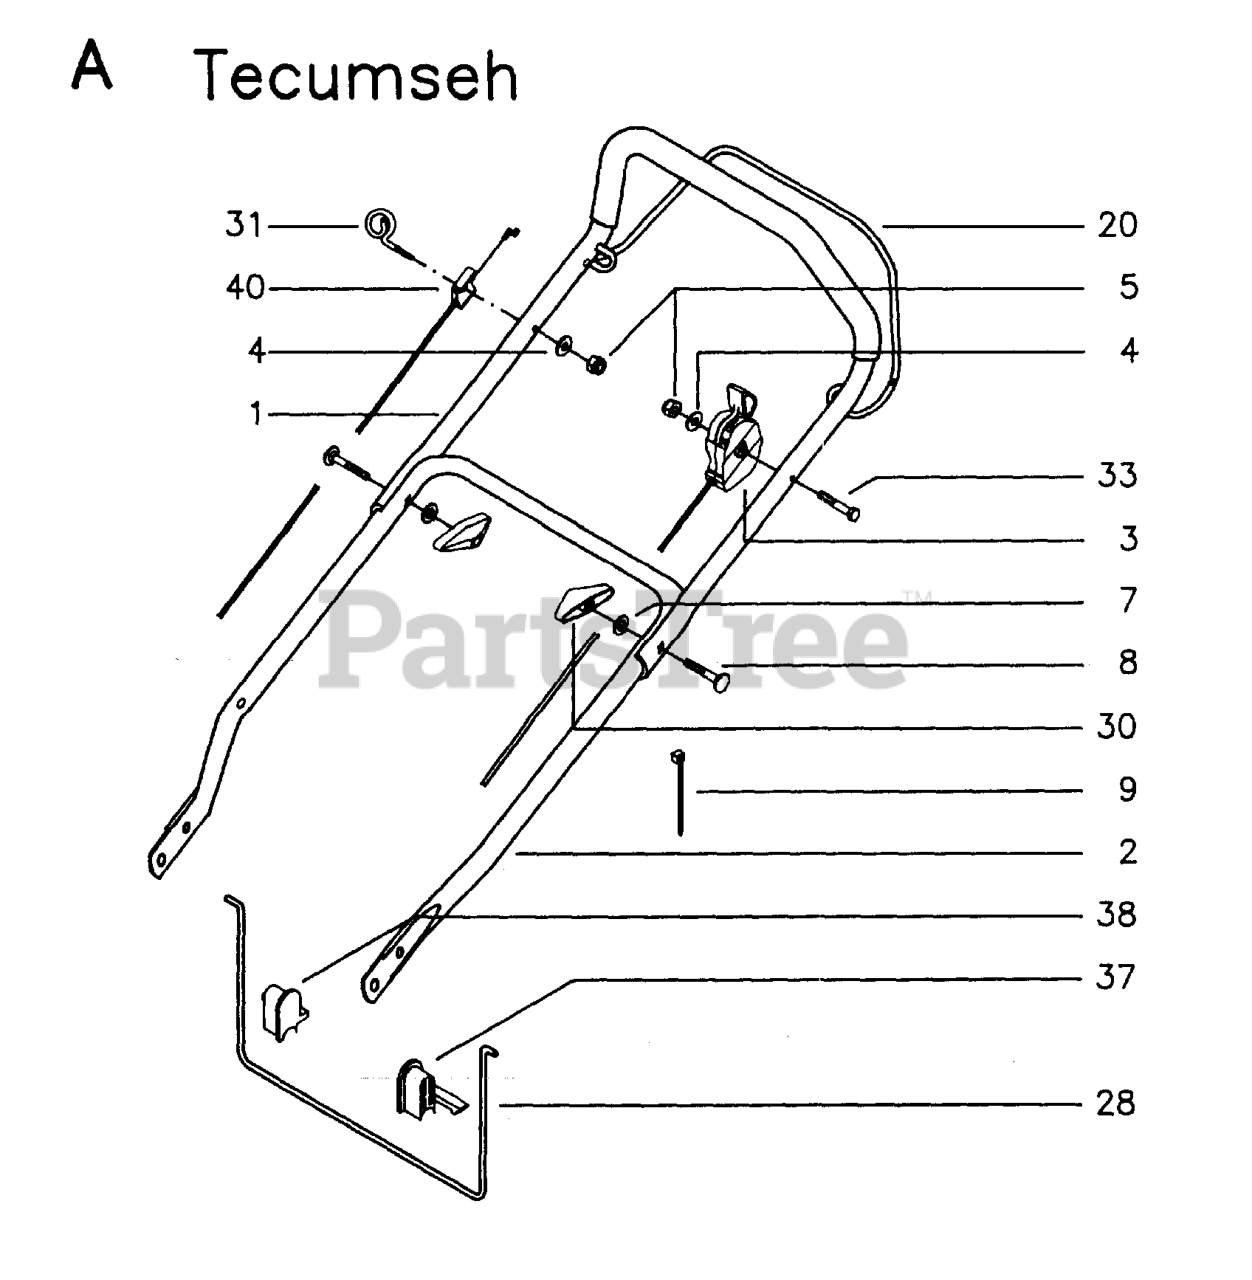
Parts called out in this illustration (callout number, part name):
2	LOWER HANDLE
5	LOCKNUT M6
28	HANDLE BAR
30	WINGNUT
